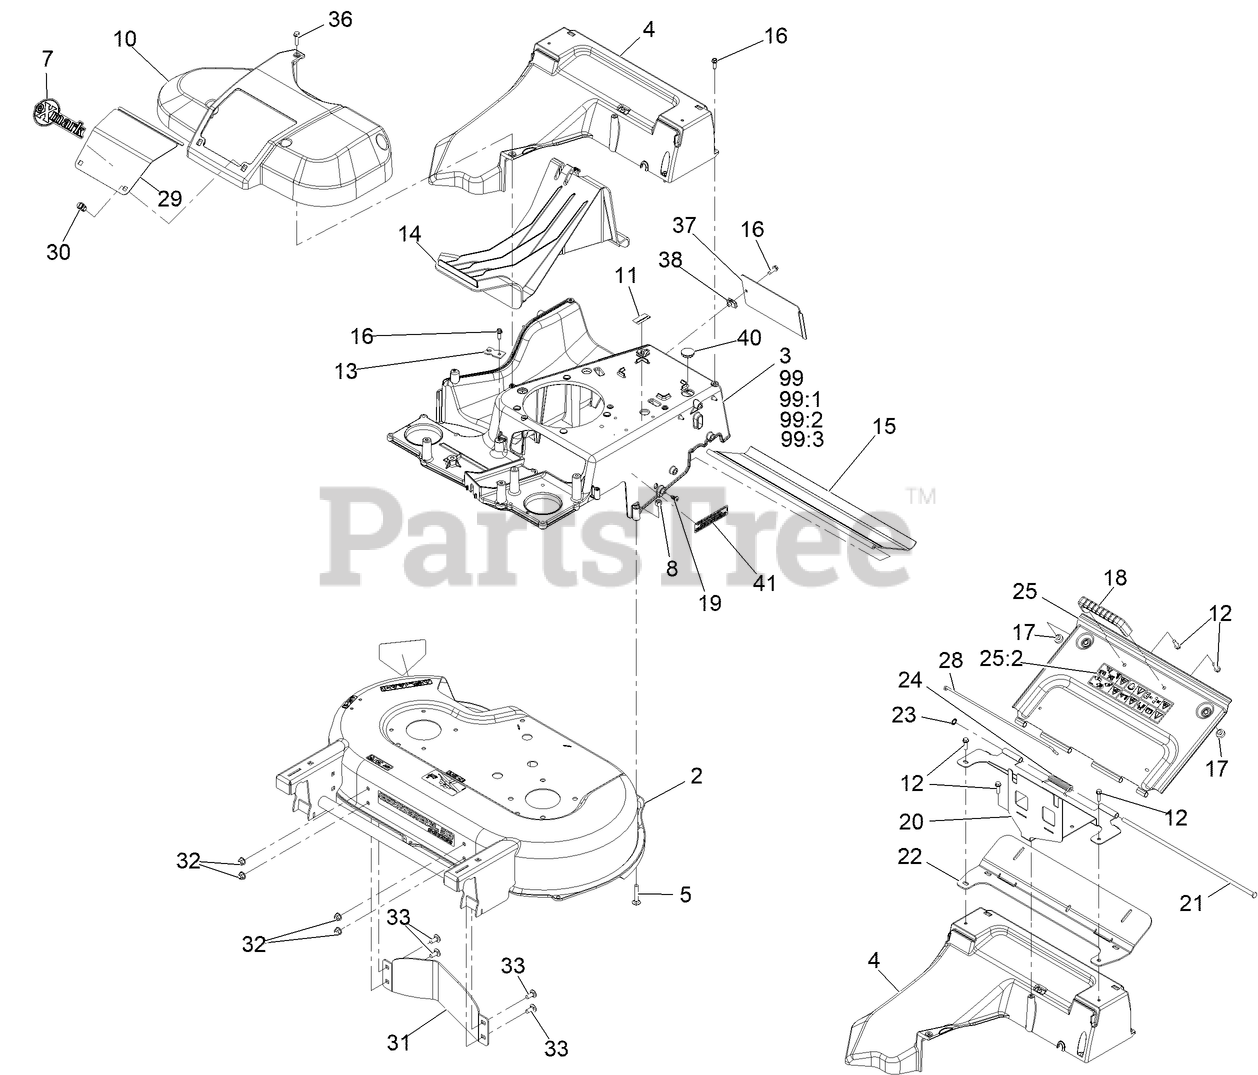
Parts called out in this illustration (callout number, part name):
2	DECK-30, X-SERIES W/DECALS
3	FRAME
5	BOLT-CAR
7	DECAL-EXMARK LOGO
8	NUT-LOCK, NI
10	COVER-BELT
11	Decal-Patent Ttco.Com
12	SCREW-HWH
13	BRACKET-CABLE, TRACTION
14	PLUG-MULCH
15	SHIELD-TRAILING
16	SCREW-HWHTF
18	HANDLE-DOOR
19	SCREW-PTH
20	Weld-Tank Mount
21	PIN-HINGE
22	SEAL-DOOR
23	RING-RETAINING
24	SPRING-TORSION, COVER
25	REAR DOOR ASM
25:2	DECAL-WARNING
28	CLIP-SEAL
29	DOOR-ACCESS
30	FASTENER
31	BAFFLE-CONTROL
32	NUT-HF, NI
33	SCREW-HSBH
36	SCREW-HWHTF
37	Cover-Frame
40	PLUG-BUTTON
41	DECAL-ARRESTOR, SPARK
99	FRAME PLATE KIT
99:1	PLATE-FRAME
99:2	SCREW-CARR
99:3	NUT-LOCK, NI
